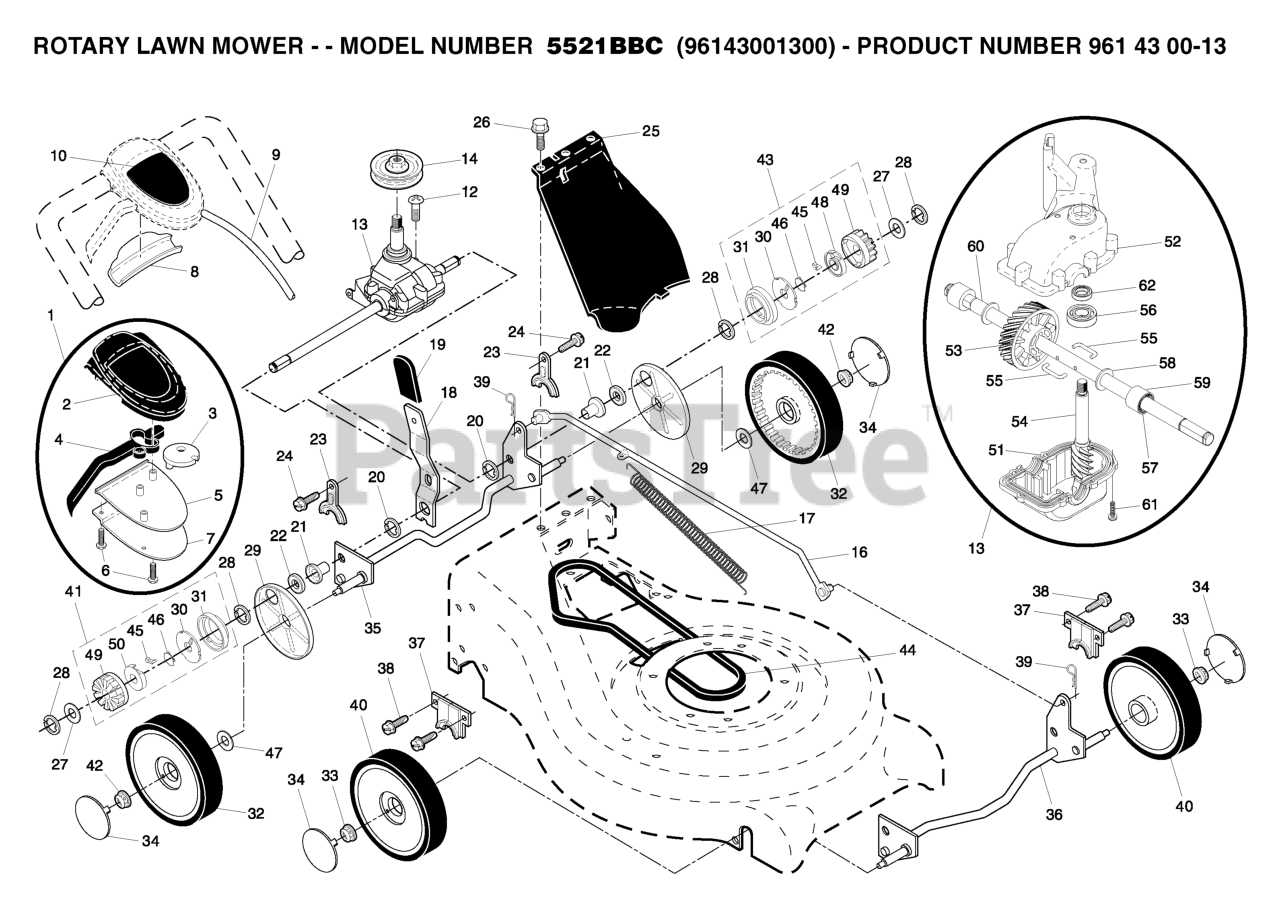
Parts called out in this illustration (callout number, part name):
1	CONTROL.DR.AW.GRY.RWGD.BLACK
2	CASE.TOP.GRAY
3	PULLEY.CAM.DRIVE.CONTROL.HV
4	LEVER, AUTOWALK DRIVE CONTROL
5	CASE BOTTOM
6	SCREW, PHILLIPS HEAD 10 X 5/8
7	BRACKET.DRIVE.CONTROL.MOUNT.BL
8	EZ WALK SNAP COVER PLATE
9	DRIVE CONTROL CABLE
10	DECAL.DRIVE.CONTROL.HV
13	TRANSMISSION.21.RWGD.EZ/AW/VS
16	ROD CONNECTING
17	SPRING
18	SPRING.SELECTOR.SPT.21
19	KNOB, SELECTOR SPRING
21	RP BEARING SUPPORT
22	BEARING, BALL
23	BRACKET
25	COVER.DRIVE.21.RWGD.MO
28	E-RING 7/16 RE
29	COVER.DUST.WHEEL
30	DISC.DRIVE.21.EZ-WALK
31	SEAL.PINION
32	KIT.WHL.9X2.RAD.BLK(SERV ONLY)
33	HEX FLANGE LOCKNT
34	HUBCAP
35	SHAFT.ASM.REAR.TORQUE
36	SHAFT ASM FRONT
37	RETAINER.FRONT.SHAFT
39	RETAINER CLIP
40	WHEEL.8X2.PR.LP.RADII.BLK
41	PINION ASSY, RH
42	NUT
43	PINION ASSY, LH
44	V-BELT
45	PAWL.DRIVE.21.EZ-WALK
46	SPRING, TORSION
47	WASHER FLUT
48	RETAINER.DRIVE.21.EZ-WALK.LT
49	GEAR, PINION
50	RETAINER, DRIVE, RH
51	CASE, LOWER
52	CASE, UPPER
53	GEAR.24.TOOTH.WALK.MOWER
54	SHAFT INPUT
55	RP.SHAFT.OUTPUT.RGD.VS/EZ
57	SEAL.OUTPUT.SHAFT
60	SHAFT OUTPUT (12215)
62	SEAL INPUT SHAFT
